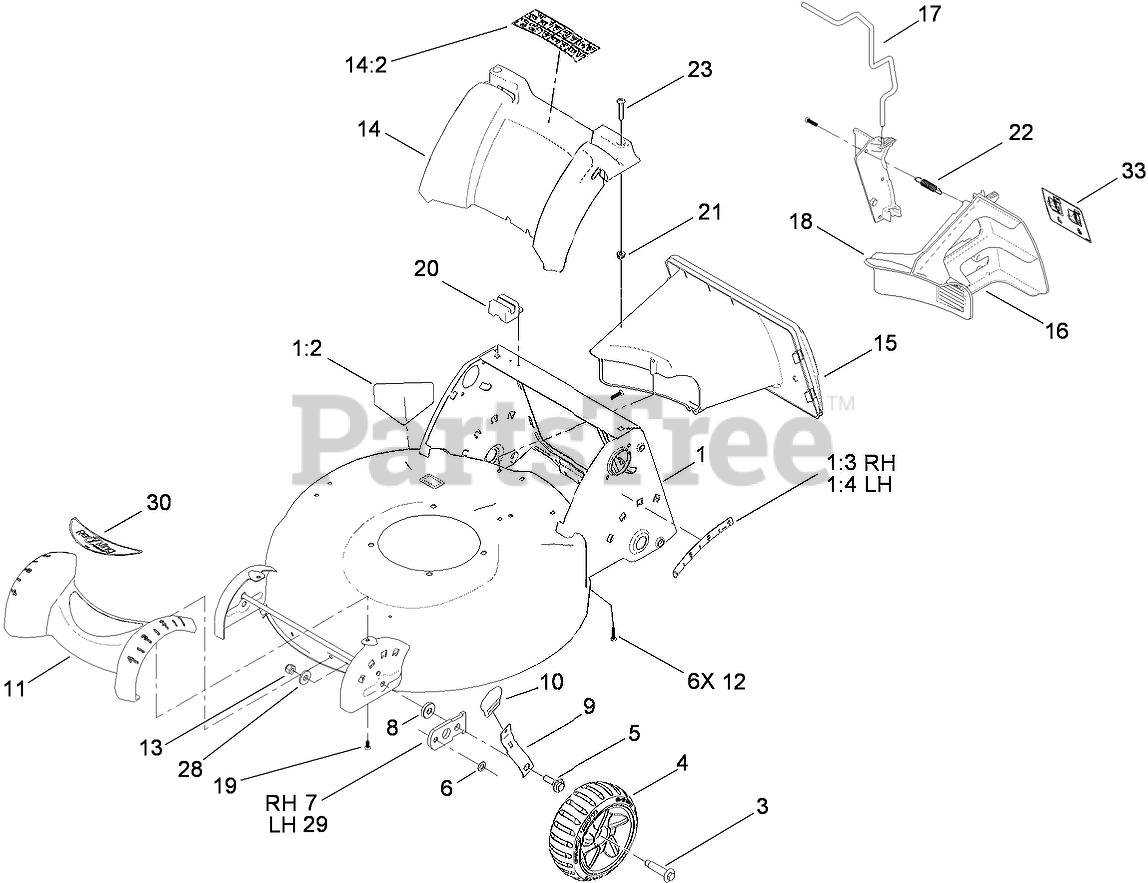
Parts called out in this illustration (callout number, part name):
1	DECK ASM
1:2	DECAL-DANGER
1:3	DECAL-HOC, RH
1:4	DECAL-HOC, LH
3	BOLT-SHOULDER
5	SCREW-SHOULDER, HWH
6	WASHER
7	ARM-PIVOT, RH
8	WASHER
9	ARM-SPRING
10	KNOB-HOC
11	COVER-FRONT
12	SCREW-PLASTITE
13	NUT-LOCK, NI
14	REAR COVER ASM
14:2	DECAL-WARNING
15	TUNNEL
16	PLUG-MULCH, LH
17	LATCH-PLUG, MULCH
18	PLUG-MULCH, RH
19	SCREW-PLASTITE
20	MODULE-SWITCH
21	NUT-CLIP
22	SPRING-EXTENSION
23	SCREW-PTH
28	WASHER-HARDENED
29	ARM-PIVOT, LH
30	DECAL-FRONT
33	DECAL-PLUG, MULCH
